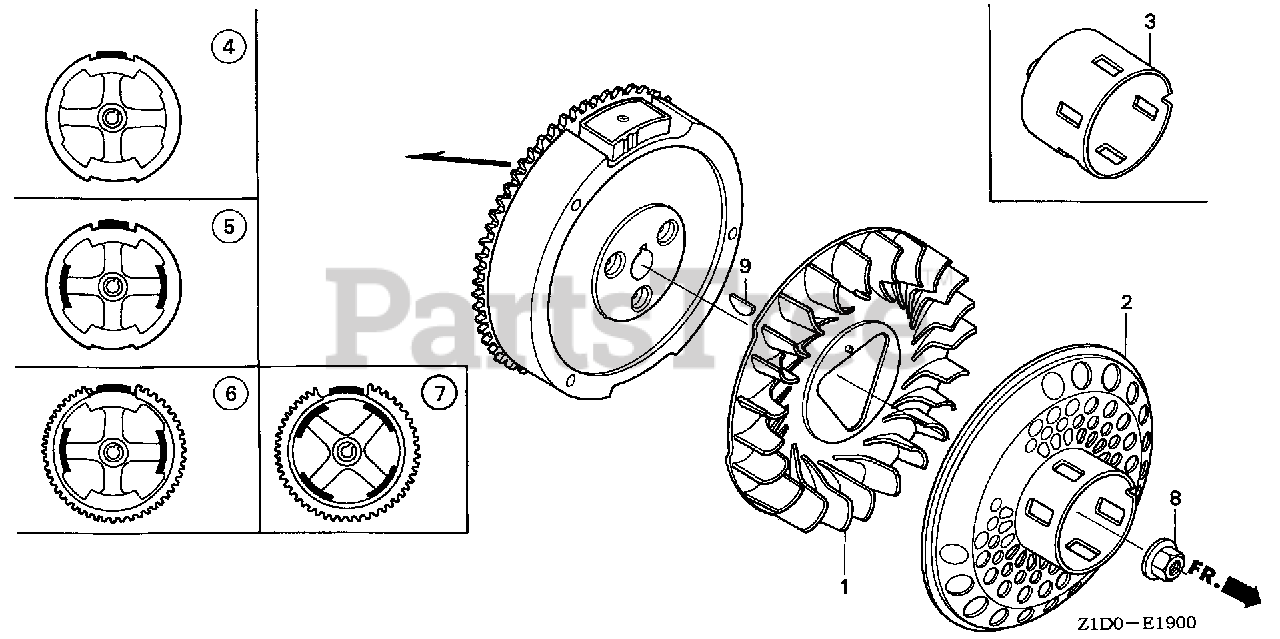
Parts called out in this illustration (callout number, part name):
1	FAN, COOLING
3	PULLEY, STARTER
8	NUT, SPECIAL (16MM)
9	KEY, SPECIAL WOODRUFF (25X18)
